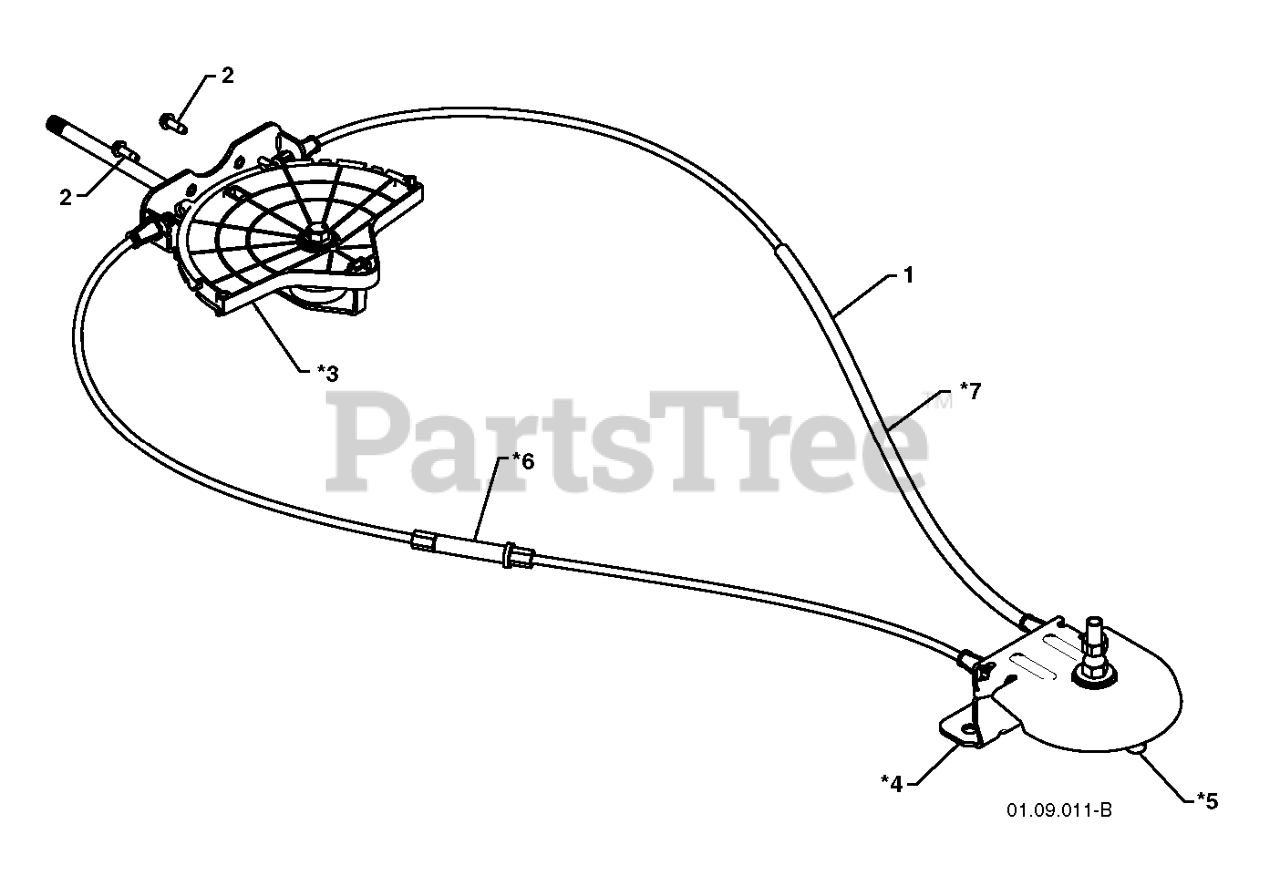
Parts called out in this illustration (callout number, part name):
1	RB LEVER.CABLE.ASM.ROTATR.PLTD
2	SCREW #10-24 X 5/8
3	CHUTE.ROT.HEAD.SERVICE
4	SNOW.PIVOT.BRKT.GRY.SERVICE
5	SNOW.PIVOT.PULLY
6	SNOW.CABLE.ASM.ADJUSTABLE.GRAY
7	SNOW.CABLE.ASM.SERVICE
